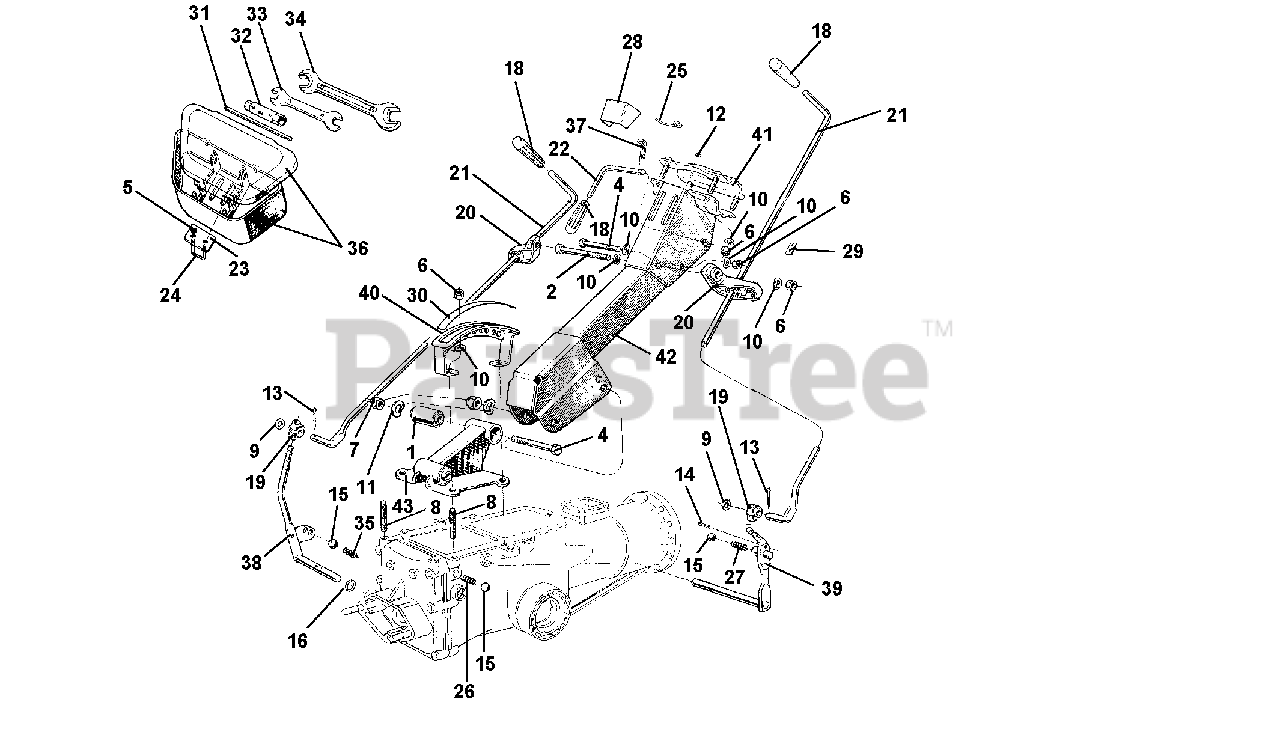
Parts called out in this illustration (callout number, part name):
1	SILENTBLOCK
2	SCREW TE M8 X 100
3	SCREW TE M10 X 70
4	SCREW M8 X 60
5	NUT, SELF LOCKING M6
6	NUT, SELF LOCKING M8
7	NUT, SELF LOCKING M10
8	STUD M8 X 38 X 14 X 20
9	WASHER P10.5 X 18
10	WASHER, LOCK 8.4
11	WASHER, LOCK 10.5
12	WASHER, LOCK FOR PINS
14	LOCKING PIN SPIRAL
15	BALL 15/32 RIV RB-11.906
16	O-RING 115 11.91 X 2.62
19	JOINT, D 10
20	SUPPORT, CONTROL ROD
21	ROD, CONTROL, POWER TILLER
22	LEVER FOR SECTOR
25	SHEATH HOOK
28	ADHESIVE LABEL 602
29	PLATE SLOW/FAST SPEEDS
30	PLATE, SPEED, MOWER
31	PARALLEL PIN D 7 X 130
32	TUBE KEY 10 - 13
33	OPEN KEY 13 - 17
34	OPEN KEY 19 - 22
35	P.T.O. SPRING
36	NEUTRAL TOOL BOX
38	P.T.O. LEVER
39	MOTOR MOWER GEARBOX LEVER
42	MOTOR MOWER STEERING COLUMN
43	SUPPORT COMPL. SILENTBLOCK
